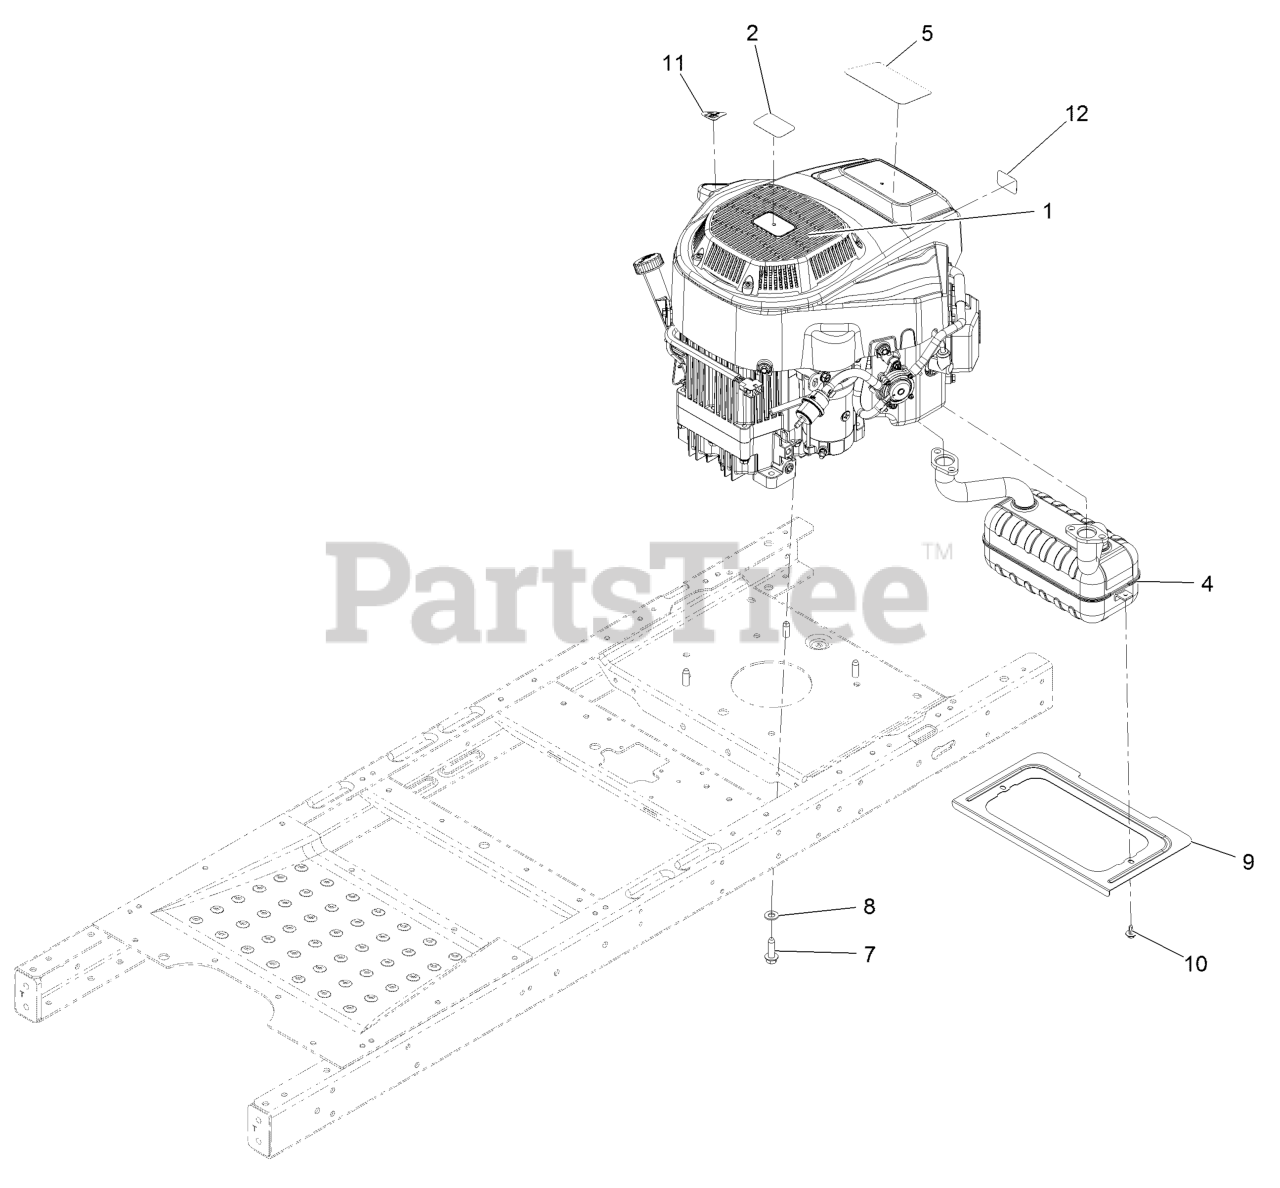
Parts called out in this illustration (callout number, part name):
4	MUFFLER
5	DECAL-ENGINE DISPLACEMENT
7	SCREW-THD
8	WASHER-FLAT
9	SHIELD-HEAT
10	SCREW-HHFTF
11	DECAL-DRAIN, OIL
12	PLACARD-INTAKE, EXMARK
